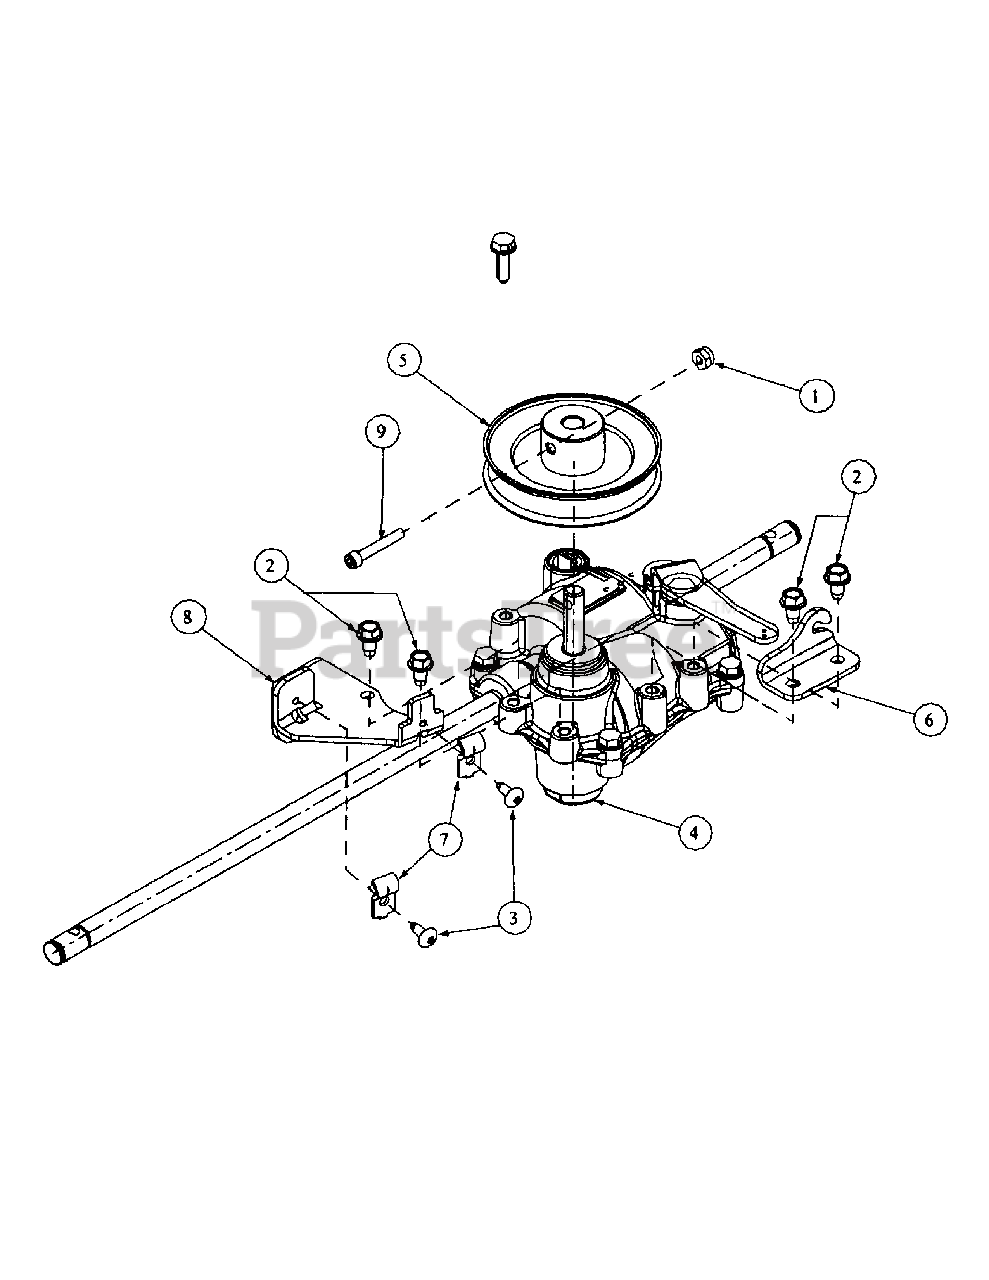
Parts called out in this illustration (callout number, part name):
1	Nylon Lock Nut, #10-24
2	Screw, TT, Hex Index Washer, 1/4-20, 0.500
3	Screw, B, #10-16, 0.500, Trustrx1
4	Complete Transmission, 3-Speed
5	Transmission Pulley, 3/8V x 3.50 OD
6	Spring Bracket Transmission
7	Cable Clamp, 3/16
8	Transmission Clutch Bracket
9	Socket Screw, 10-24 x 1.25
